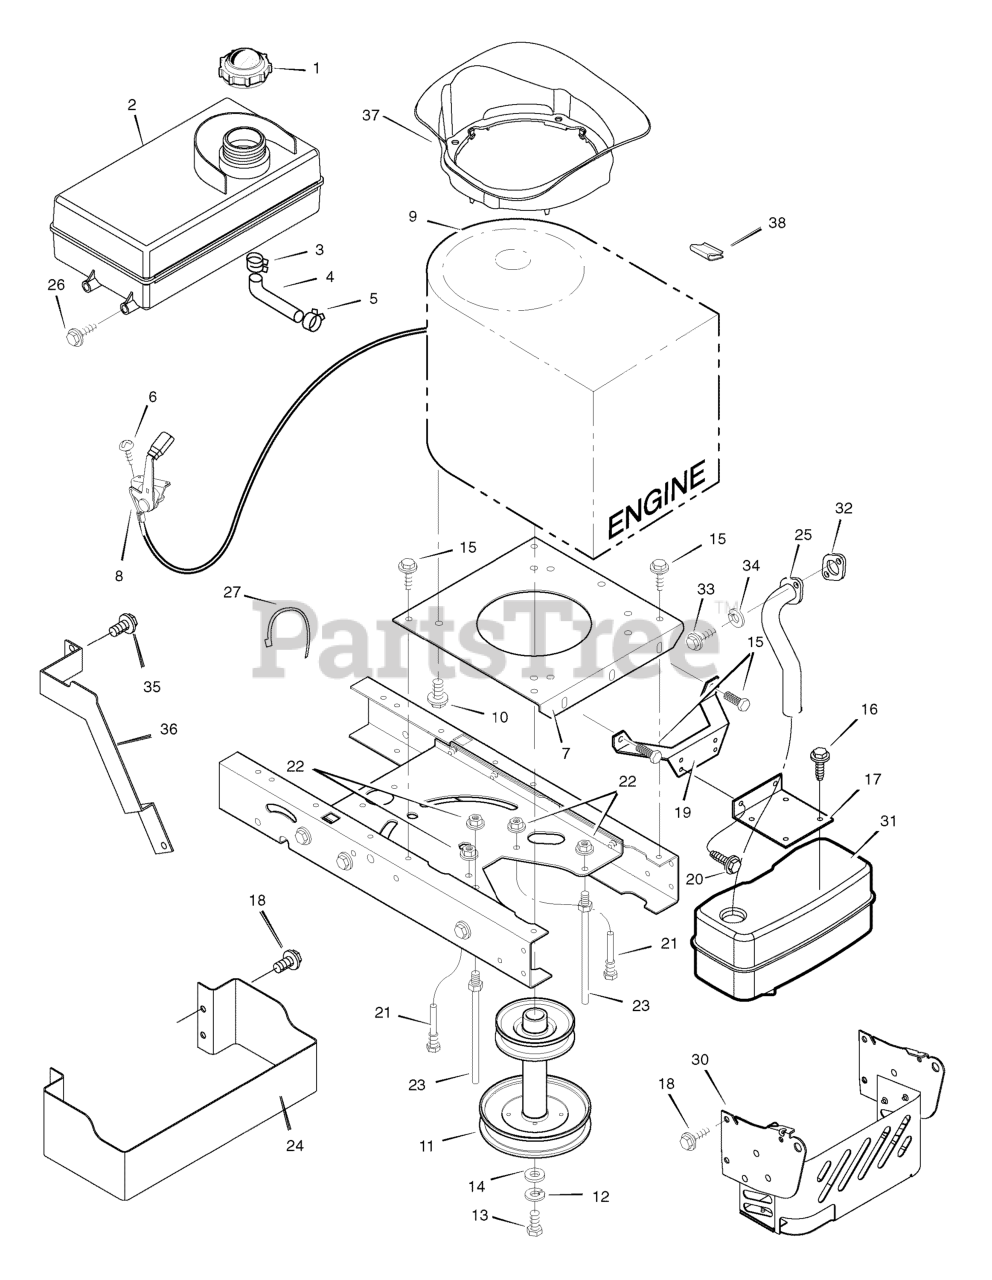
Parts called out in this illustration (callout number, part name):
1	Fuel Cap
2	TANK, Fuel 1.4 Gal.
3	Hose Clamp
4	Fuel Line (Must cut to length)
5	Hose Clamp
7	PLATE, Engine
8	THROTTLE CONTROL
9	Engine, Briggs & Stratton *
10	BOLT, Engine Mount
11	STACK PULLEY ASSEMBLY
12	LOCKWASHER
13	BOLT, Hex
17	BRACKET, Muffler
19	BRACKET, Muffler Mount
21	GUIDE, Belt
22	NUT, Flange
23	GUIDE, Belt
24	GUARD, Heat Shield
25	EXHAUST TUBE, Single
27	TIE, Strap, 5.38 Long
30	SHIELD, Heat
31	MUFFLER
32	GASKET, Exhaust
34	WASHER
35	BOLT, Washer Hex Head
36	GUARD, Exhaust Pipe
37	PLENUM, X1 M28/31
38	CLIP, Wire Adhesive
